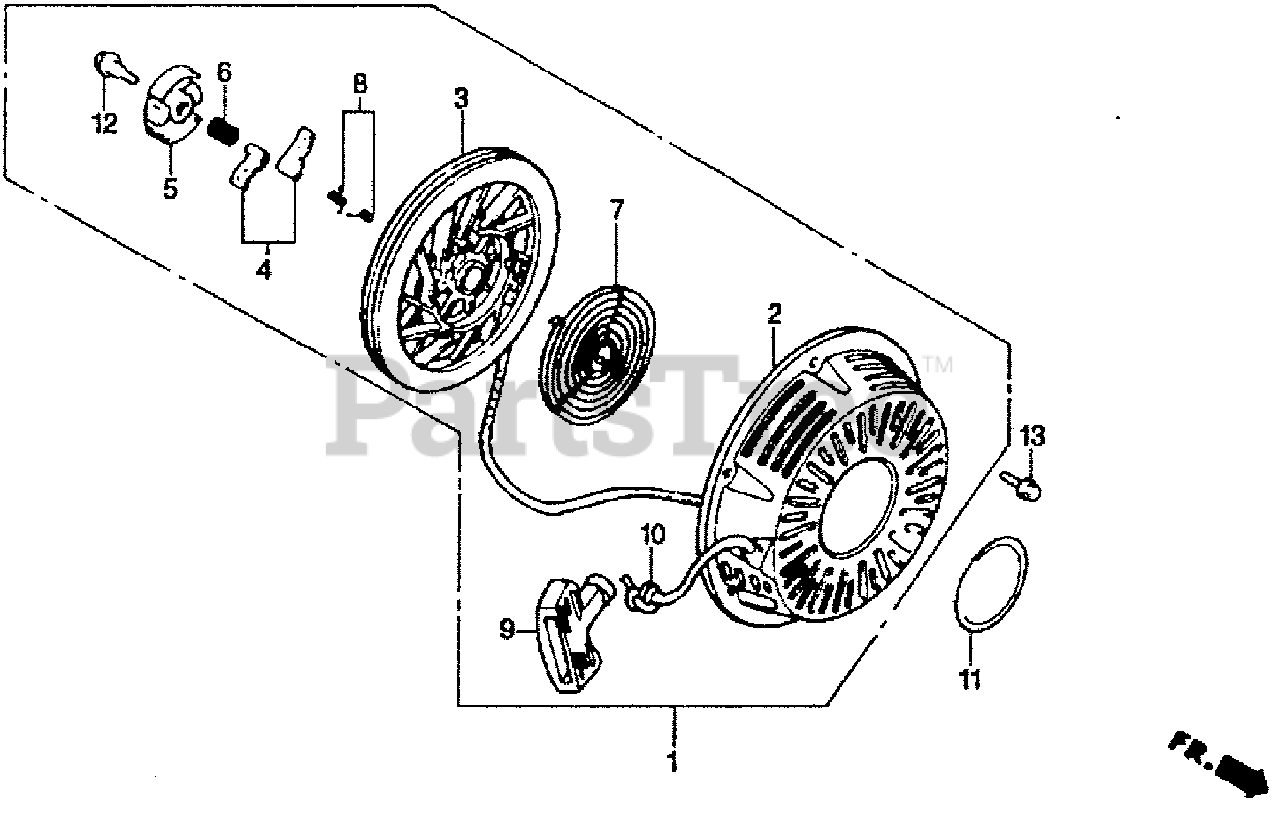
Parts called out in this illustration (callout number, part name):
1	STARTER ASSY., RECOIL *R280* (POWER RED)
1	STARTER ASSY., RECOIL *R8* (BRIGHT RED)
2	CASE, RECOIL STARTER *R8* (BRIGHT RED)
3	REEL, RECOIL STARTER
4	RATCHET, STARTER
5	GUIDE, RATCHET
6	SPRING, FRICTION
7	SPRING, RECOIL STARTER
8	SPRING, RETURN
9	KNOB, RECOIL STARTER
10	ROPE, RECOIL STARTER (#5X55")
11	EMBLEM (INTERNAL)
12	SCREW, SETTING
13	BOLT, FLANGE (6X8)
